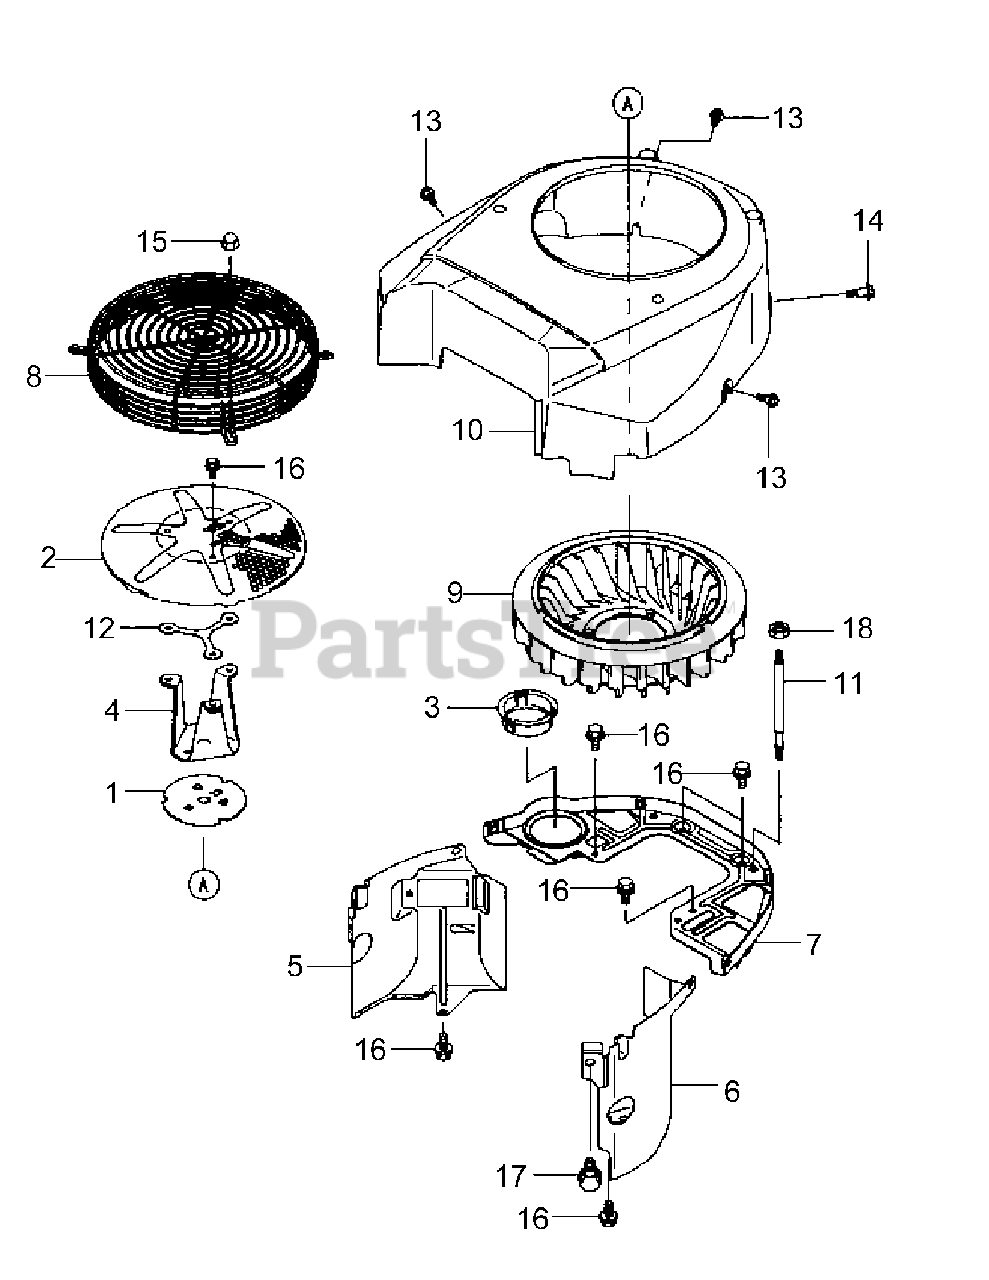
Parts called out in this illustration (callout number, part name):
4	BRACKET
5	ENGINE SHROUD
6	ENGINE SHROUD
7	ENGINE SHROUD
12	SPACER
14	BOLT
16	FLANGED BOLT
17	FLANGED BOLT
